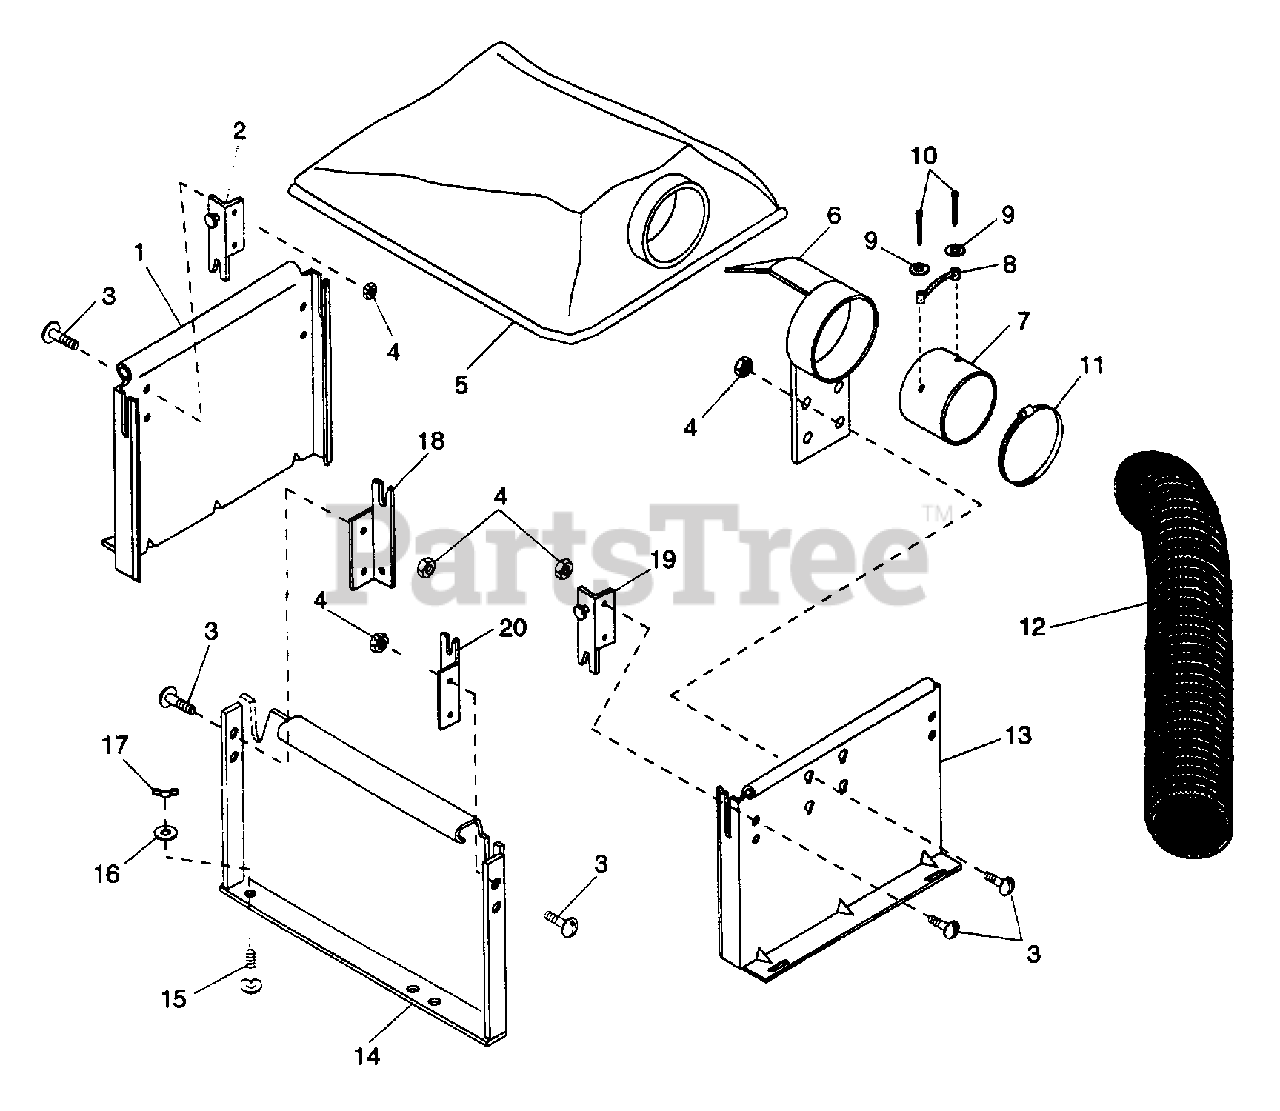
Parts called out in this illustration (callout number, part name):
1	REAR GATE
2	RIGHT GATE PIN
3	SCR-MCH .25-20X.50 SLRH
4	NUT-LK-FLG .250-20 PL
5	CART COVER
6	HOSE CONNECTION
7	INNER TUBE
8	BATTERY STRAP
9	WSHR-FL-STL .188X.438X.049 PL
10	PIN-COTR .12X1.0 PL
11	CLAMP-HOSE WRM 2.13/8.62X.56
12	HOSE 6 X 72
13	CART FRONT W/ DECAL
14	CART SIDE
15	BLT-RDHDSQNK .25-20X.75
16	WSHR-FL-STL .250X.562X.049 PL
17	NUT-WING .250-20
18	REINFORCEMENT R.H.
19	LEFT GATE PIN
20	REINFORCEMENT L.H.
